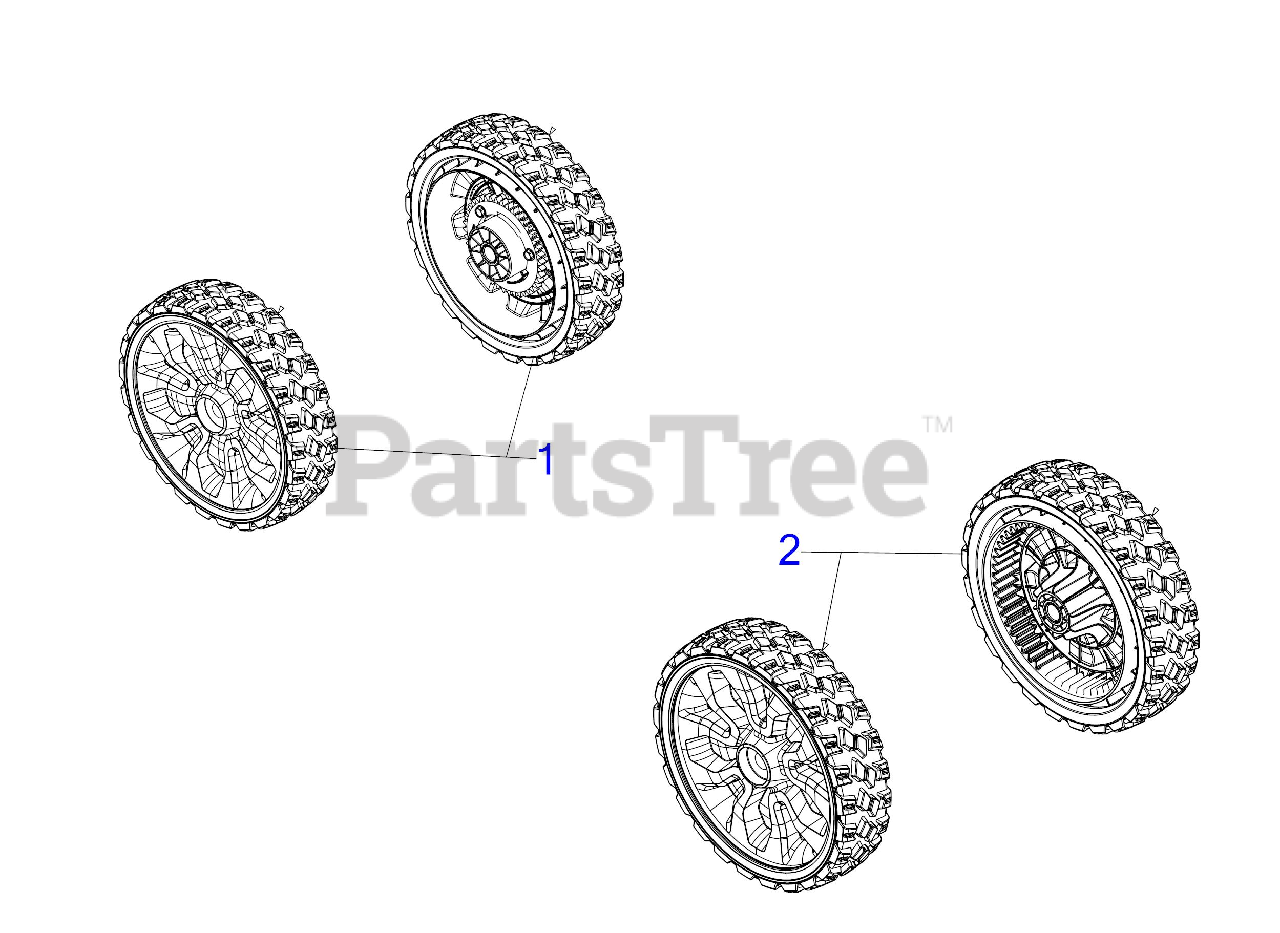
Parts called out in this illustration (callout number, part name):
1	DRIVE WHEEL ASSEMBLY (8 x 2 GRAY)
1	REAR DUST COVER
2	DRIVE WHEEL ASSEMBLY (8 x 2 GRAY)
2	FRONT DUST COVER
